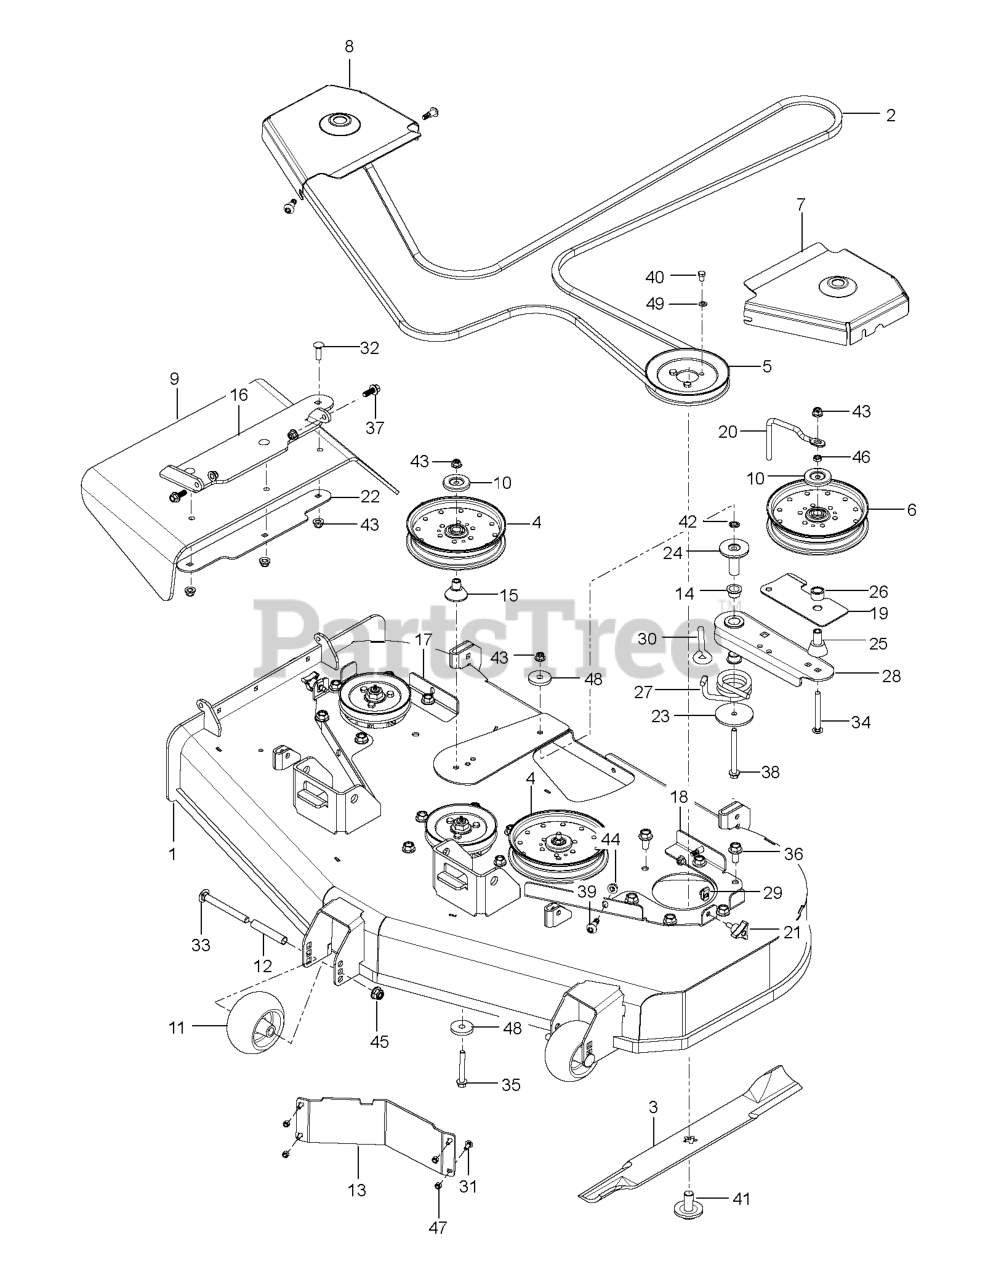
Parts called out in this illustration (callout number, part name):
1	DECK.SVC.W/DECALS.48".10GA.ORG
2	BELT.5V.158.75.(EPDM)
3	BLADE 17" HIGHT LIFT
4	GSPW PULLEYS
5	PULLEY - 5.25
6	PULLEY - IDLER 7"
7	COVER.PULLEY.LH.PNT
8	COVER.PULLEY.RH.PNT
9	CHUTE.DISCHARGE
10	DUST SHIELD
11	ROLLER, GAUGE .635 BORN
12	TUBE, ROLLER AXLE
13	BAFFLE, DIVERTER 54"/60" LH
14	BEARING, FLANGE
15	BEARING, IDLER ARM
16	BRACKET.CHUTE.ORG
17	BRACKET PULLEY COVER MOUNT LH
18	BRACKET PULLEY COVER MOUNT RH
19	BELT.GUIDE.LOWER.PLATE.MS431
20	KEEPER KEEPER., BELT
21	KNOB W/STUD
22	PLATE.BACKING.DISCHARGE.CHT.BK
23	PLATE.SPRING.RETAINER
24	SHAFT.MOUNT.ARM.IDLER
25	SPACER
26	SPACER.PULLEY.INTERMEDIATE
27	SPRING.TORSION.DECK.IDLER.TMSN
28	ARM.PNT.WLD.TENSIONR.IDLER.BLK
29	U-CLIP 5/16-18 NUT RETAINER
30	EYE BOLT, 3/8 X 4"
31	1/4-20X3/4 CARR BLT
32	BOLT.3/8-14X1.25
33	RHSNB 1/2-13 X 4.75 GR5 ZD
34	BOLT.RDHD SQNK 3/8-16 X 3-1/2
35	HHFS 3/8-16 X 2-3/4 GR5 ZD
36	HHFS 1/2-13 X 1 GR5 ZD
37	HHFS 3/8-16 X 1 GRD 5 ZD
38	HHFS 3/8-16 X 4 GR5 ZD
39	SCREW.SHLDR.3/8 X 1/2.5/16-18
40	HCS 5/16-18 X 1/2 GR 5 ZD
41	BLADE BOLT/WASHER
42	NUT 3/8 PALNUT RTNG BLK PHOS
43	NUT 3/8-16 HEX FLG NYLOC ZD
44	5/16-18 NYLOC FLANGE NUT
45	NUT, 1/2-13 HEX FLG NYLOC ZD
46	NUT 3/8-16 HEX JAM
47	NUT.1/4-20.HEX.NYLOC.ZD
48	SPINDLE WASHER
49	WASH 5/16 DISC SPRING ZD
